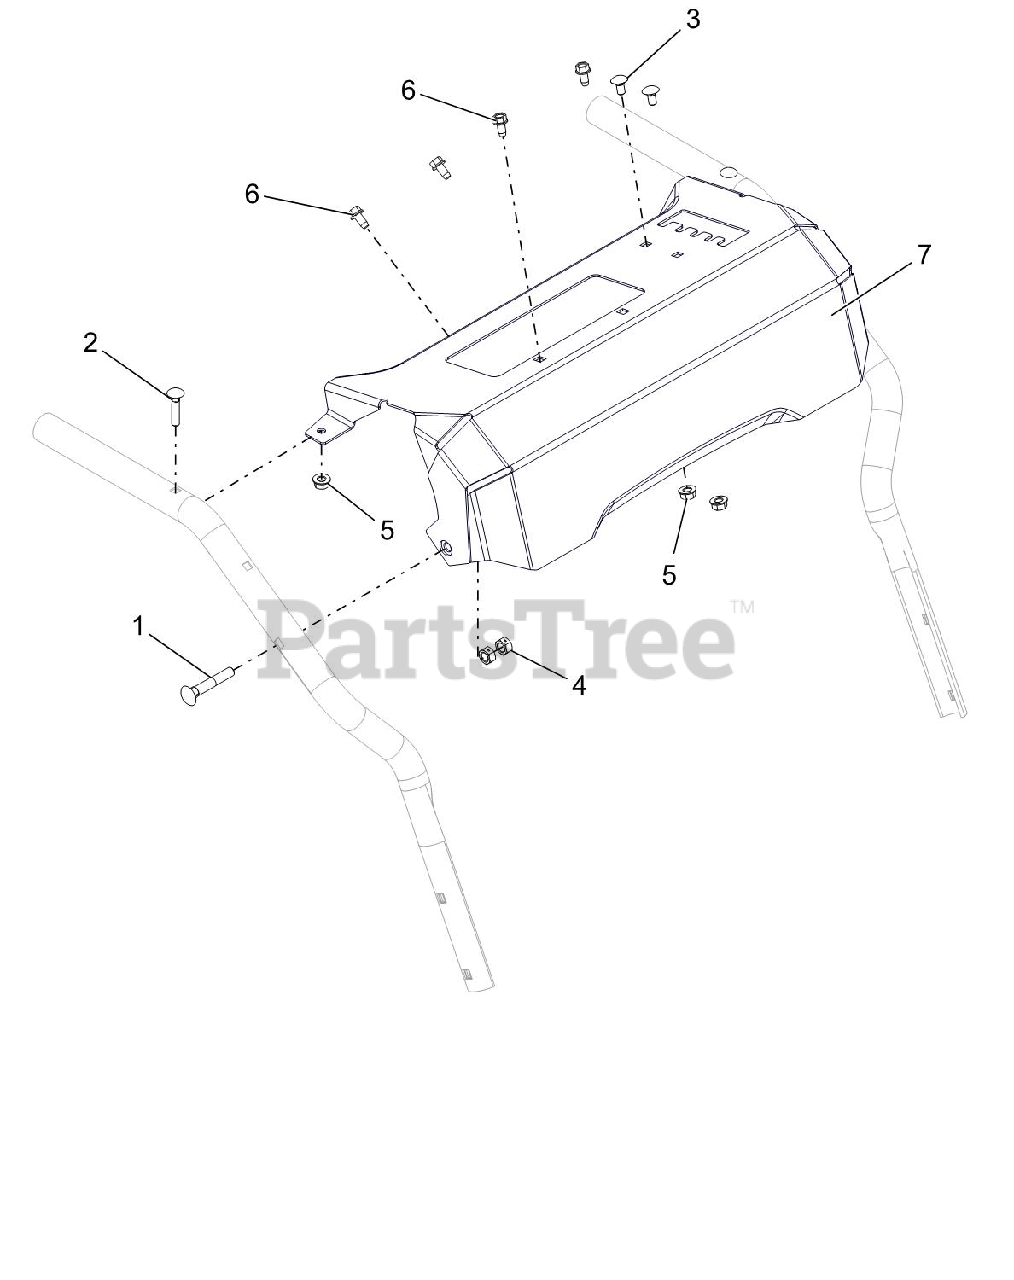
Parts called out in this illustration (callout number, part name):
1	BLT-RDHDXLSQNK .31-18X2.0 G5YZ
2	BLT-RDHDXLSQNK.25-20X1.25 G5ZC
3	@BLT-RDHDSQNK .25-20X.50 G5YZ
4	@NUT-LK-CTR .31-18 YWZC
5	@NUT-LK-TOP-FLG .25-20 YWZC
6	SCR-TAP .25-20X.50 HWH TR YWZ
7	CTRL PANEL W/DECAL-SNOTEK MANU
